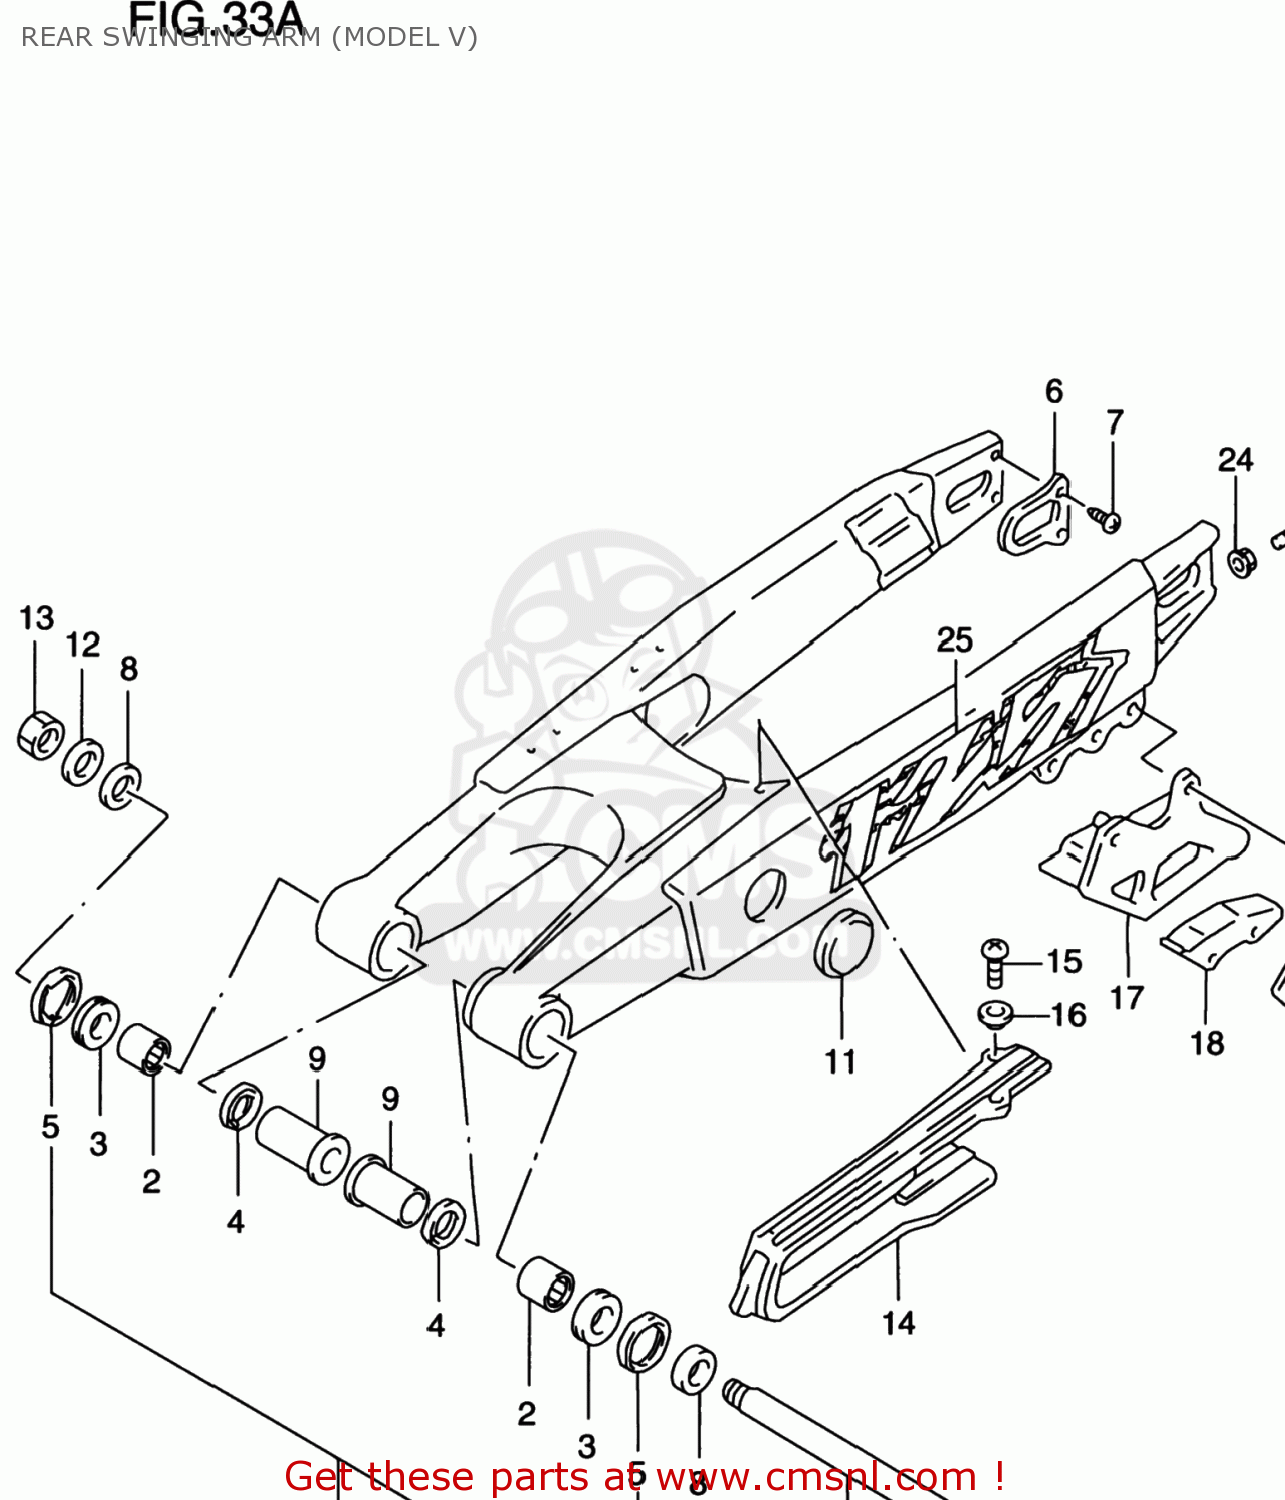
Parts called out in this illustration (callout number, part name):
1	SWING ARM ASSEMBLY,REAR
2	BEARING(22X29X30)
3	BEARING(22X35X2)
4	SEAL,OIL(22X29X4)
5	SEAL,RR SWGARM PIVOT OUTER
6	PLATE,SWING ARM,REAR
7	SCREW(5X8)
8	SPACER,RR SWGARM PIVOT OUTER
9	SPACER,SWGARM PIVOT INNER
10	SHAFT,RR SWINGINGARM PIVOT
11	CAP(OD:45)
12	WASHER, FIXED DRIVE FACE
13	NUT
14	BUFFER,CHAIN TOUCH DEFENSE
15	SCREW
16	WASHER
17	GUIDE,CHAIN
18	DEFENSE,CHAIN GUIDE
19	PLATE,CHAIN GUIDE OUTER
20	SCREW
21	SCREW(6X40)
22	WASHER,CHAIN ADJUSTER
23	BOLT(8X50)
24	NUT
25	EMBLEM,SWING ARM
